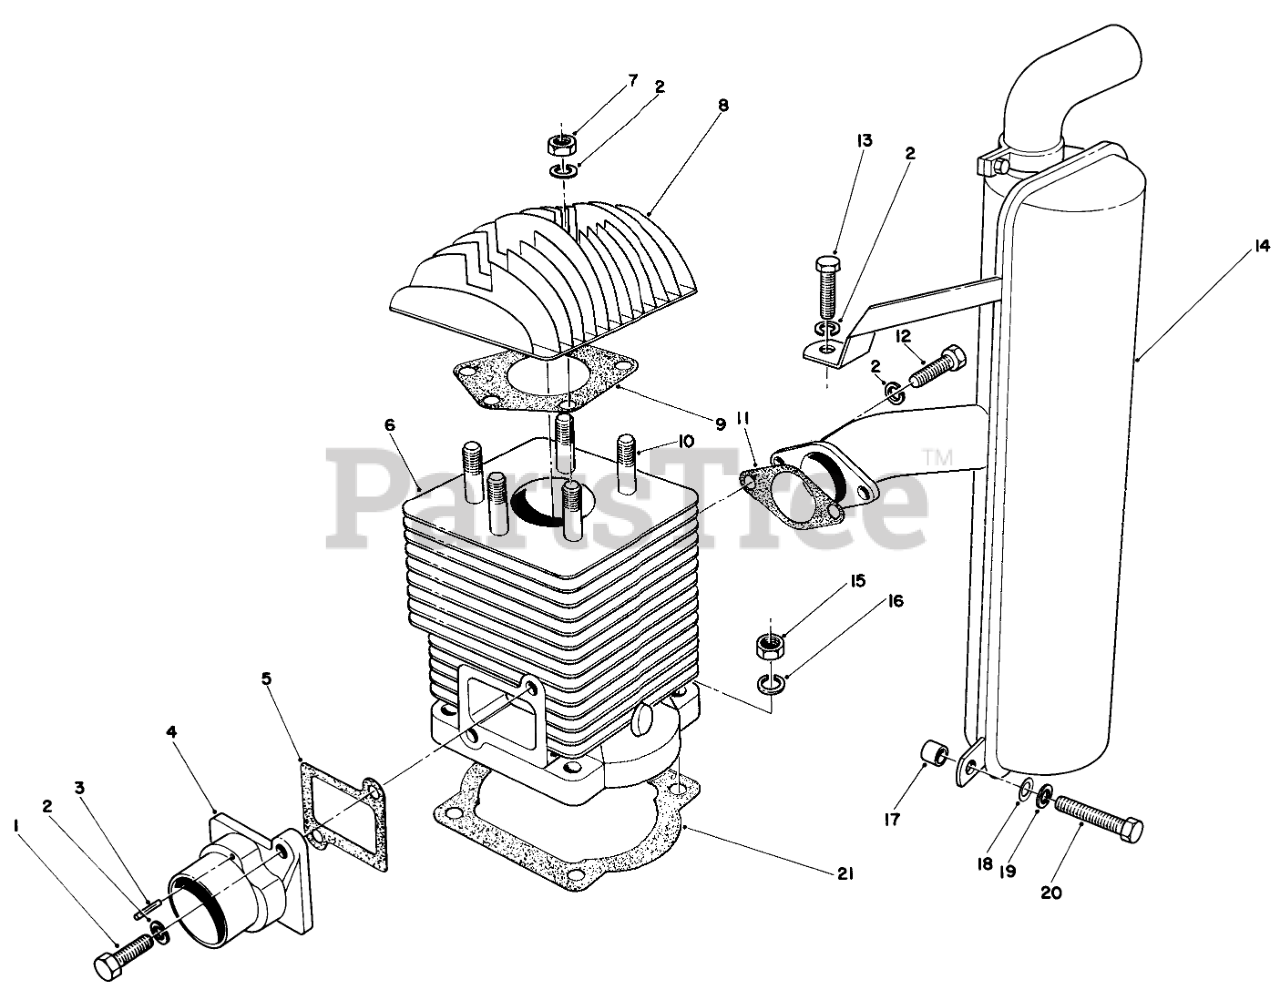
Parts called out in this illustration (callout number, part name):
1	Capscrew-Socket Head
2	Lockwasher
3	Pin-Wrist
4	Manifold-Carburetor
5	Gasket
6	Cylinder
8	Cylinder Head
9	CYL. HEAD GASKET
11	Gasket
12	Screw-Hex Head
13	Screw-Hex Head
14	Muffler
16	Lockwasher
17	Spacer-Tube
18	Washer
19	Lockwasher
20	Screw-Hex Head
21	Gasket
